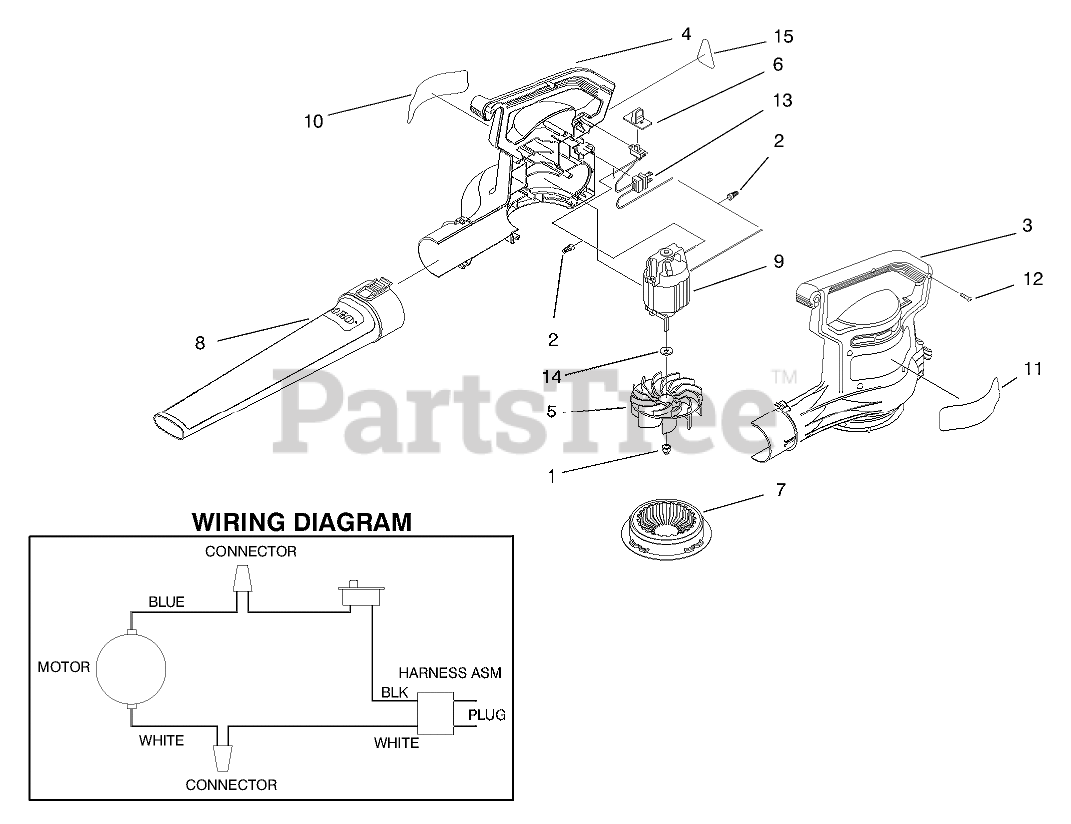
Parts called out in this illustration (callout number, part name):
1	NUT-LOCK, NI
2	CONNECTOR-NUT, WIRE
3	HOUSING - LH
4	HOUSING - RH
5	IMPELLER, BLOWER
6	COVER-SWITCH
7	COVER - INLET
8	TUBE - BLOWER SHORT
9	MOTOR - 1.00" STACK
10	DECAL - POWER SWEEP
11	LABEL STOCK - BLOWERS
12	SCREW-PPH
13	HARNESS ASSEMBLY
14	WASHER
15	DECAL - INFORMATION
